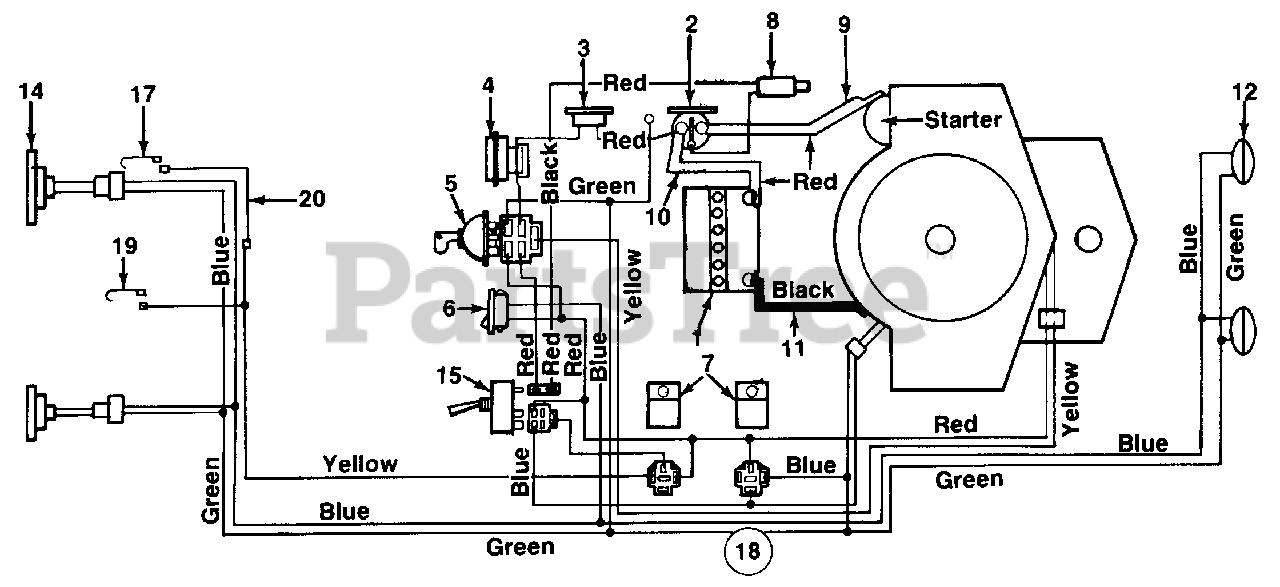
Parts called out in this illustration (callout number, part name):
2	Solenoid
3	Circuit Breaker
4	Ammeter
5	Ignition Switch
6	Light Switch
7	Relay
8	Safety Switch
9	Electric Wire 14" Lg.
10	Electric Wire 7.5" Lg.
11	Ground Wire 7.5" Lg.
12	Headlight
14	Taillight
15	Switch
17	Spring Switch
18	Wire Harness
19	Spring Switch
20	Transmission Ext. Wire
